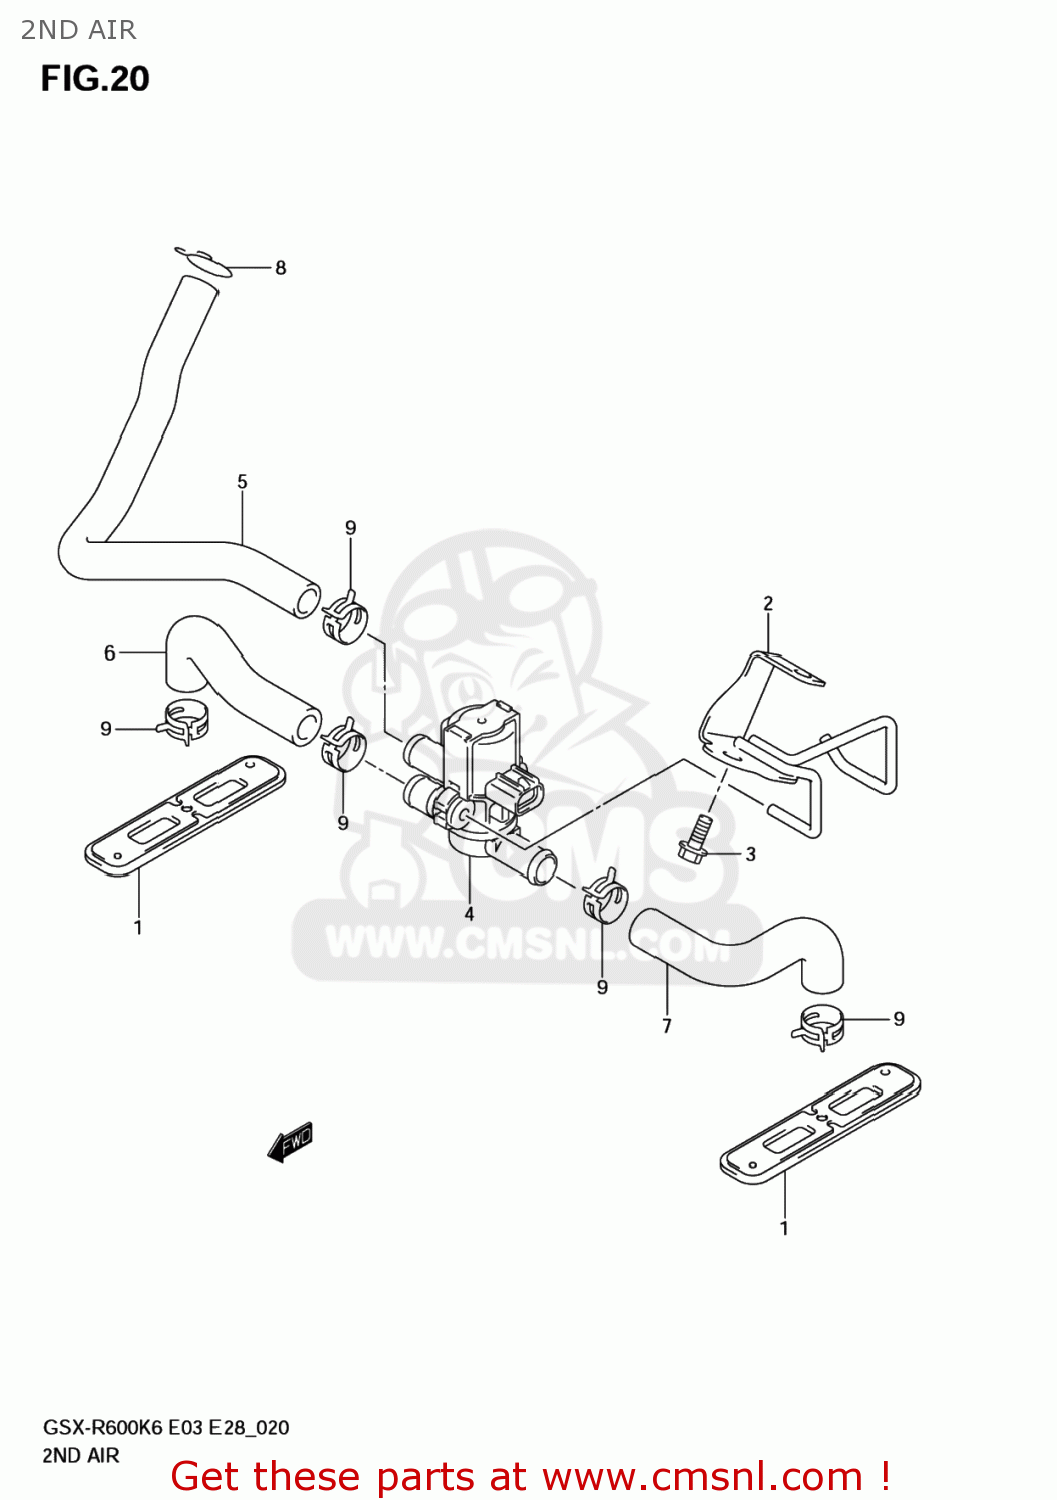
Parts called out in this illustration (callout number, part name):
1	VALVE ASSY,2ND
2	BRACKET COMP,2
3	BOLT
4	VALVE ASSY,AIR
5	HOSE,2ND AIR CLEANER
6	HOSE,2ND AIR VALVE,R
7	HOSE,2ND AIR VALVE,L
8	CLIP
9	CLIP
